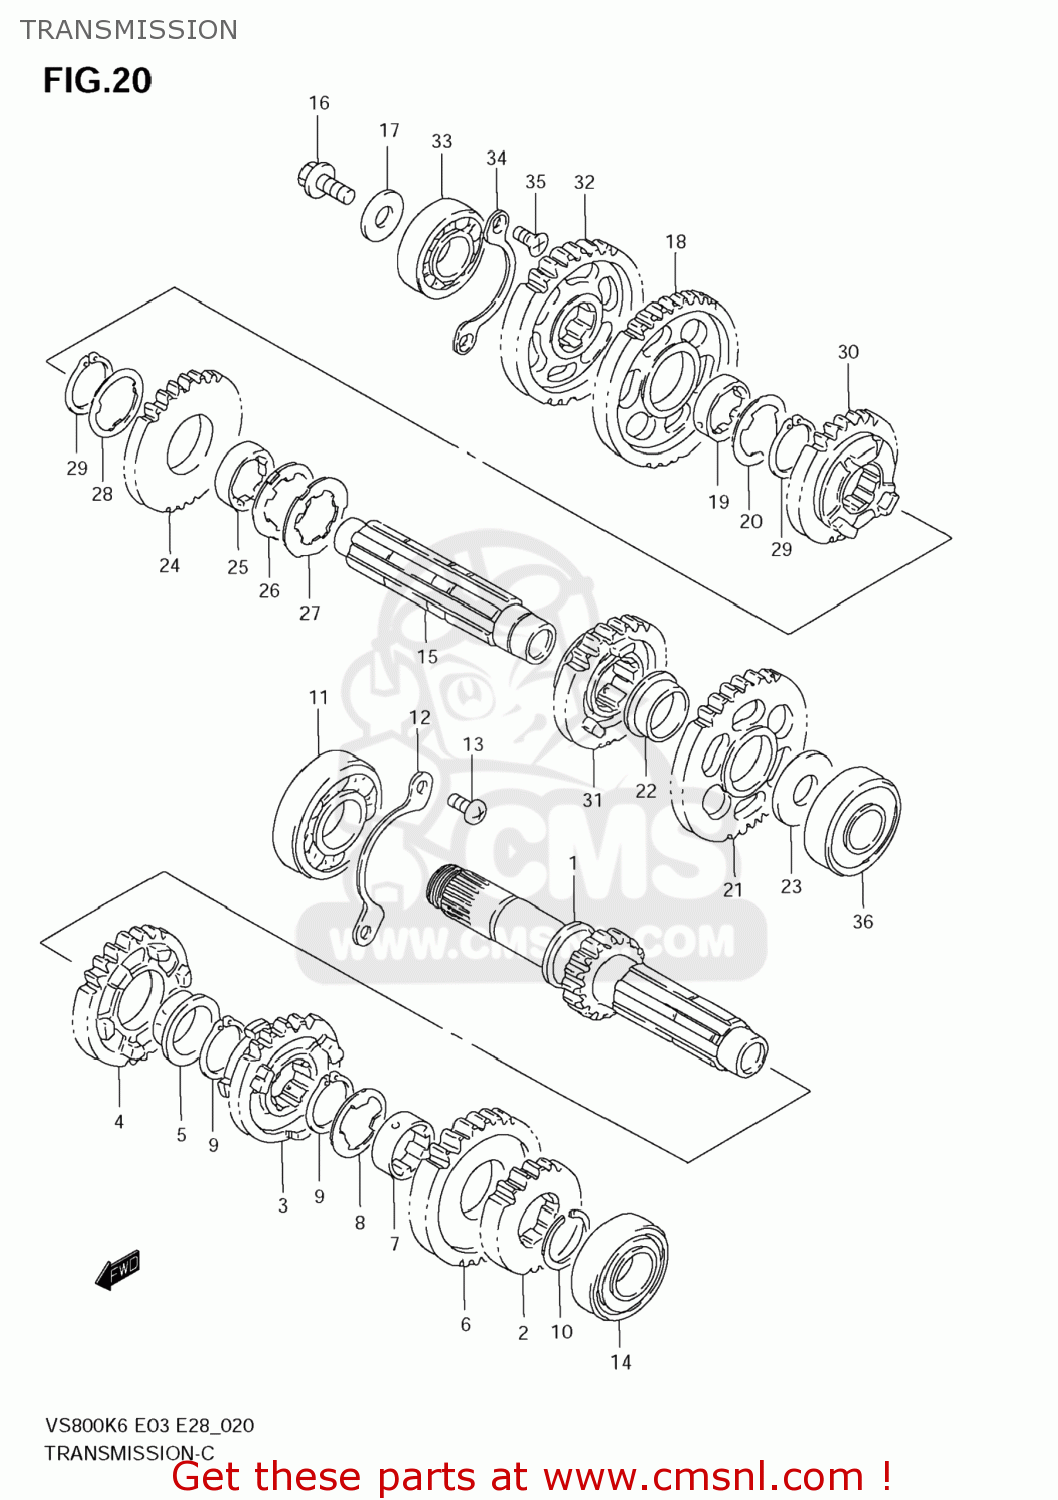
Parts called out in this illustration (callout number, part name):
1	COUNTERSHAFT(NT:14)
2	GEAR,2ND DRIVE(NT:19)
3	GEAR,3RD DRIVE(NT:22)
4	GEAR,4TH DRIVE(NT:25)
5	BUSH
6	GEAR,5TH DRIVE
7	BUSH,6TH DRIVE GEAR
8	WASHER,LOCK
9	RING,SNAP
10	CIRCLIP
11	BEARING(25X62X17)
12	RETAINER,CNTR SHAFT BEARING
13	BOLT(6X12)
14	BEARING(20X47X14)
15	SHAFT,DRIVE
16	NOZZLE,DRIVE SHAFT
17	WASHER
18	GEAR,1ST DRIVEN(NT:32)
19	BUSH
20	WASHER,LOCK
21	GEAR,2ND DRIVEN(NT:31)
22	BUSH
23	SHIM(20X34X1)
24	GEAR,3RD DRIVEN(NT:27)
25	BUSH
26	WASHER
27	WASHER,LOCK
28	WASHER,LOCK
29	CIRCLIP
30	GEAR,4TH DRIVEN(NT:25)
31	GEAR,5TH DRIVEN
32	GEAR,REDUCTION DRIVE(NT:30)
33	BEARING(20X52X15)
34	RETAINER,DRIVE SHAFT BEARING
35	SCREW(6X12)
36	BEARING(20X52X15)
